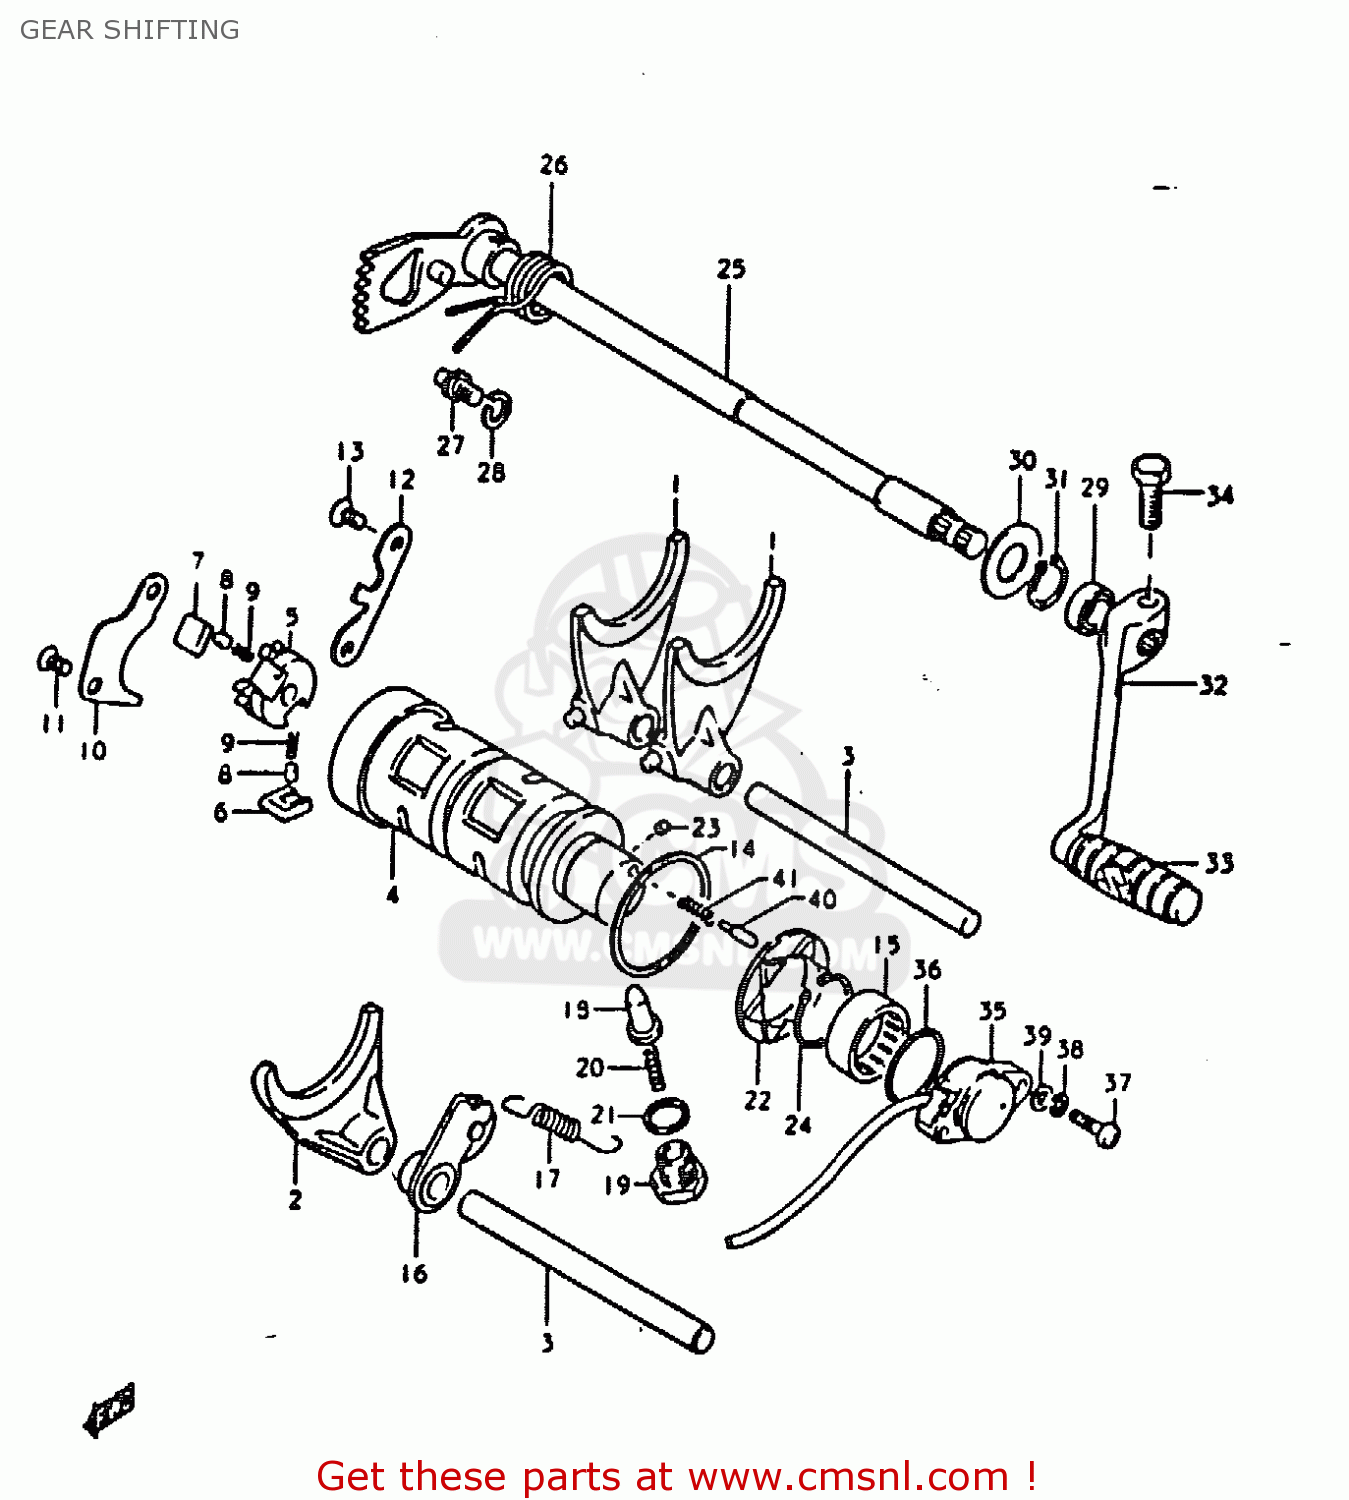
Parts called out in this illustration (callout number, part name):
1	FORK,GEAR SHIFT NO.1
2	FORK,GEAR SHIFT NO.3
3	SHAFT,GEAR SHIFT FORK
4	CAM,GEAR SHIFT
5	RETAINER,GEAR SHIFT CAM
6	PAWL,GEAR SHIFT NO.1
7	PAWL,GEAR SHIFT NO.2
8	PIN(5X8)
9	SPRING
10	LIFTER,GEAR SHIFT PAWL
11	SCREW
12	GUIDE,GEAR SHIFT CAM
13	SCREW
14	WASHER(40X45X1)
15	BEARING(25X32X12)
16	STOPPER,GEAR SHIFT CAM
17	SPRING
18	STOPPER,GEAR SHIFT CAM NO.2
19	HOLDER,GEAR SHIFT CAM STOP SPR
20	SPRING
21	GASKET(14X19.2X2) (NAS)
22	PLATE,GEAR SHIFT CAM STOPPER
23	PIN 4X6
24	CIRCLIP
25	SHAFT,GEAR SHIFT
26	SPRING
27	STOPPER,GEAR SHIFT CAM
28	WASHER
29	OIL SEAL
30	WASHER (12.5X27X1.6)
31	SPRING,RETAINER
32	LEVER ASSY,GEAR SHIFT
33	RUBBER,GEAR SHIFT PEDAL
34	BOLT
35	TERMINAL BASE,NEUTRAL SWITCH
36	O-RING (D:2.4 ID:26.2)
37	SCREW 5X20
38	LOCK WASHER
39	WASHER
40	PIN(5X15.5)
41	SPRING
